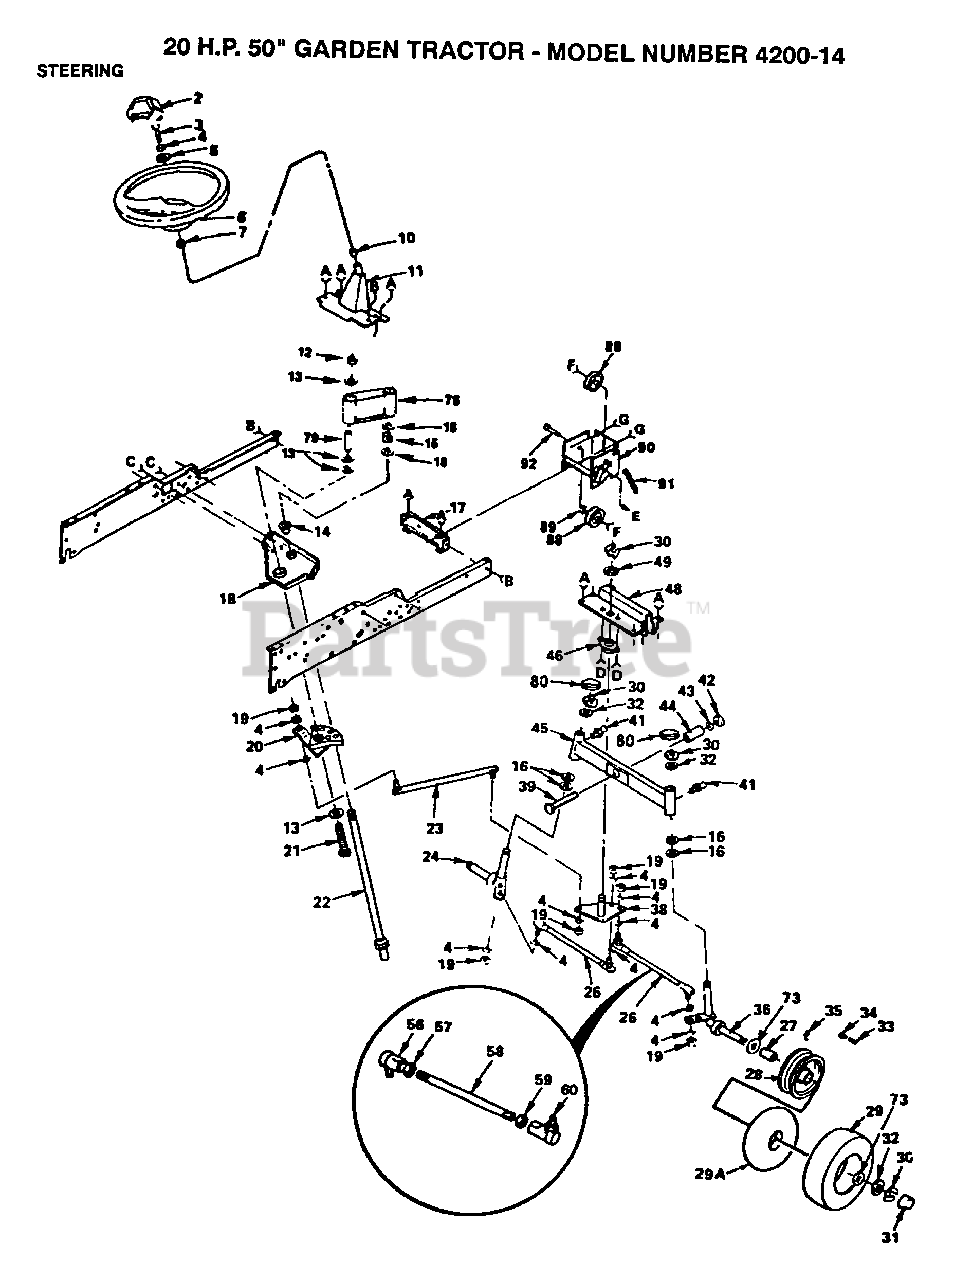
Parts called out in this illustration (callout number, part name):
3	BOLT
4	LOCKWASHER
5	WASHER T
7	ADAPTER LT
10	"T, BEARING"
11	SUPPORT ASSY T
12	NUT LTV
13	WASHER GT
14	"FLANGE GT, BEAR."
15	KLIP RING
16	WASHER .T
17	FRAME BRACKET GT
20	SECTOR T
21	BOLT T
22	SHAFT STEERING GT
23	LINK.DRAG.T
27	"FLANGE, BEARING"
29A	TUBE.16X6.5/7.5-8
30	RING
31	HUB CAP
32	WASHER
33	VALVE CAP
34	VALVE STEM LT
35	FITTING LT
38	"T, BELLCRANK"
39	BOLT
41	ZERK M
42	NUT X
43	WASHER
48	AXLE BRACKET T
49	WASHER
57	NUT
58	ROD TIE
59	NUT
63	SCREW
64	BOLT
65	BOLT
67	NUT.HEX.3/8-16UNC
73	WASHER
76	COLLAR
79	TUBE T
80	CAP
82	SPLIT SPACER YTV
83	WASHER
85	BOLT
86	BUSHING LT
87	WASHER
88	IDLER-INSIDE T
89	WASHER T
90	IDLER BRKT T
91	SPRING
